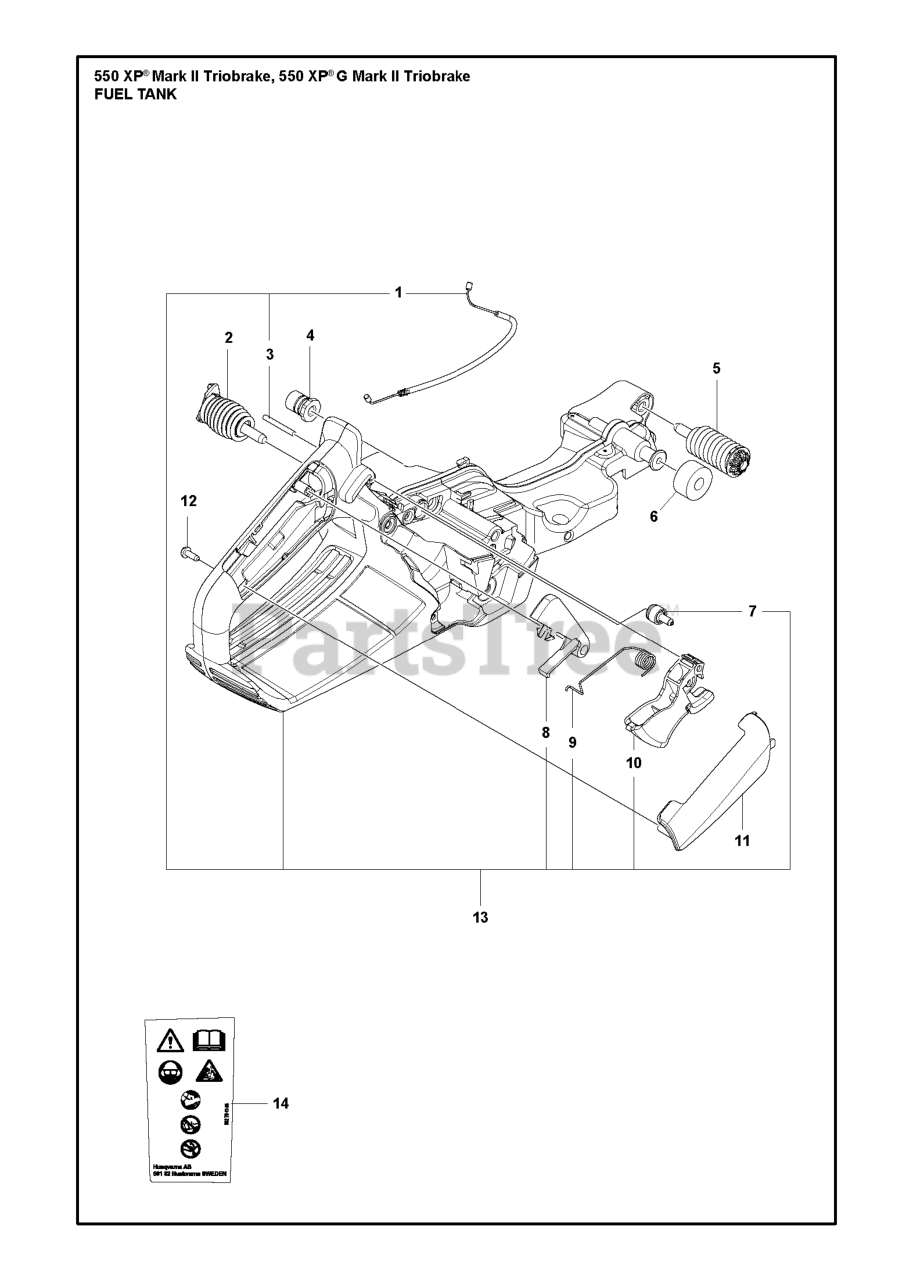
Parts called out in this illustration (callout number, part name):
1	THROTTLE CABLE ASSY 545/550 M
2	Antivibration El
4	LATERAL SUPPORT
5	ANTIVIBRATION ELEMENT FRONT
6	DEFLECTION LIMITER
7	FUEL TANK VENT
8	THROTTLE LOCKOUT
11	HANDLE INSERT
12	SCREW CITXPANT
